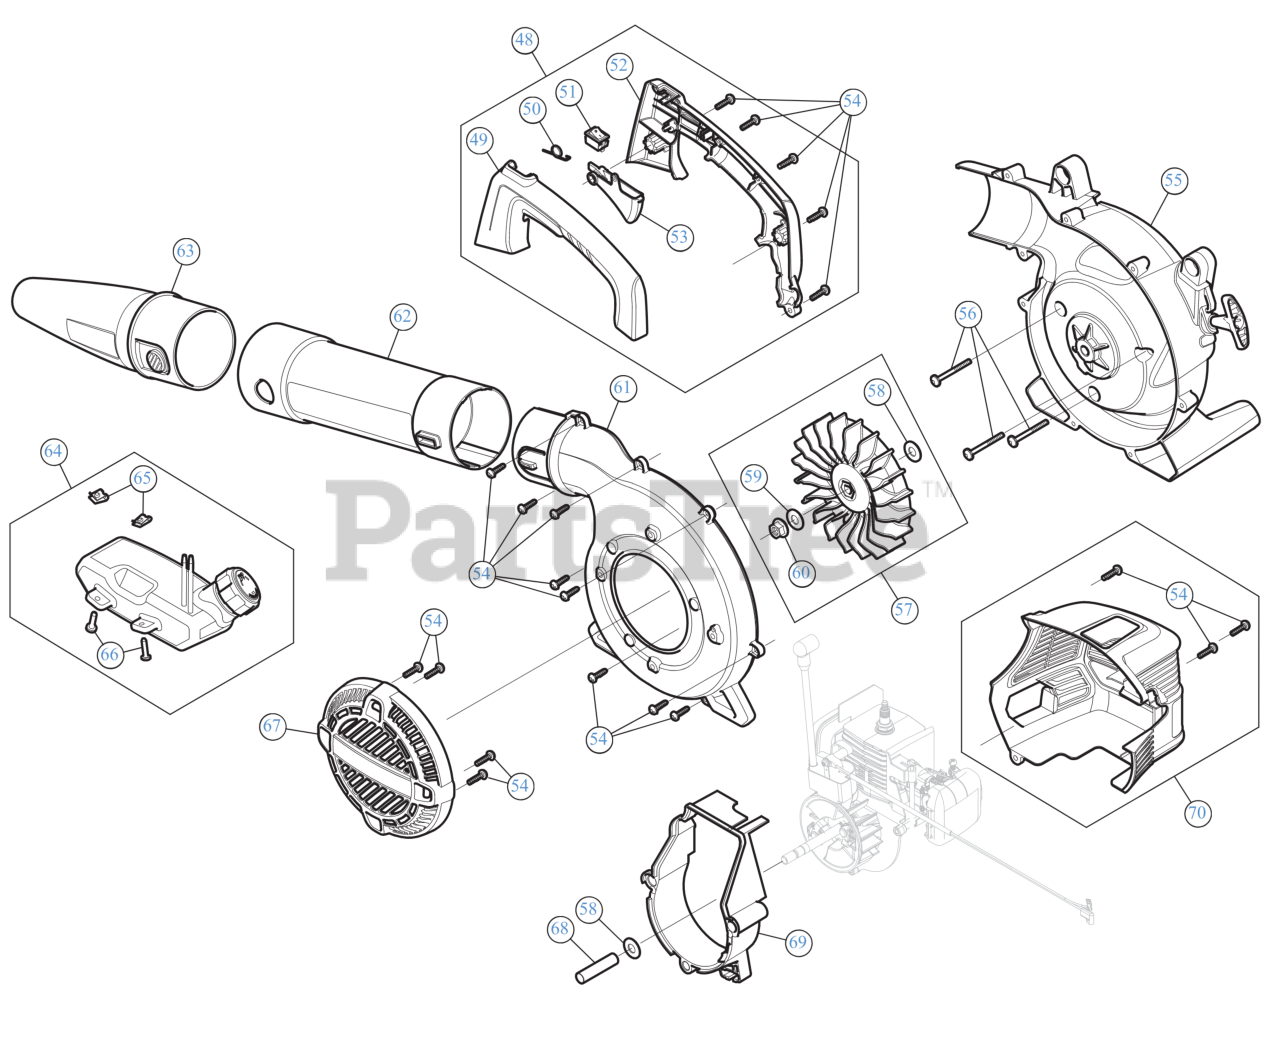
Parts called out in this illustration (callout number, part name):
48	HANDLE
49	HANDLE (LH)
50	TRIGGER SPRING
51	SW, MOMENTARY ON/O
52	HANDLE (RH)
53	THROTTLE TRIGGER
54	SCREW 8-16 x 3/4
55	IMPELLER HOUSING ASSEMBLY
56	SCREW 10/32
57	IMPELLER ASSEMBLY
58	FLAT WASHER
59	LOCK WASHER
60	NUT 3/8-24
61	IMPELLER HOUSING
62	TUBE UPPER
63	NOZZLE
64	FUEL TANK ASSEMBLY
65	NUT, TINNERMAN U-T
66	SCREW:10-6 x .75
67	INTAKE COVER
68	SPACER
69	ENGINE ADAPTER
70	ENGINE COVER
